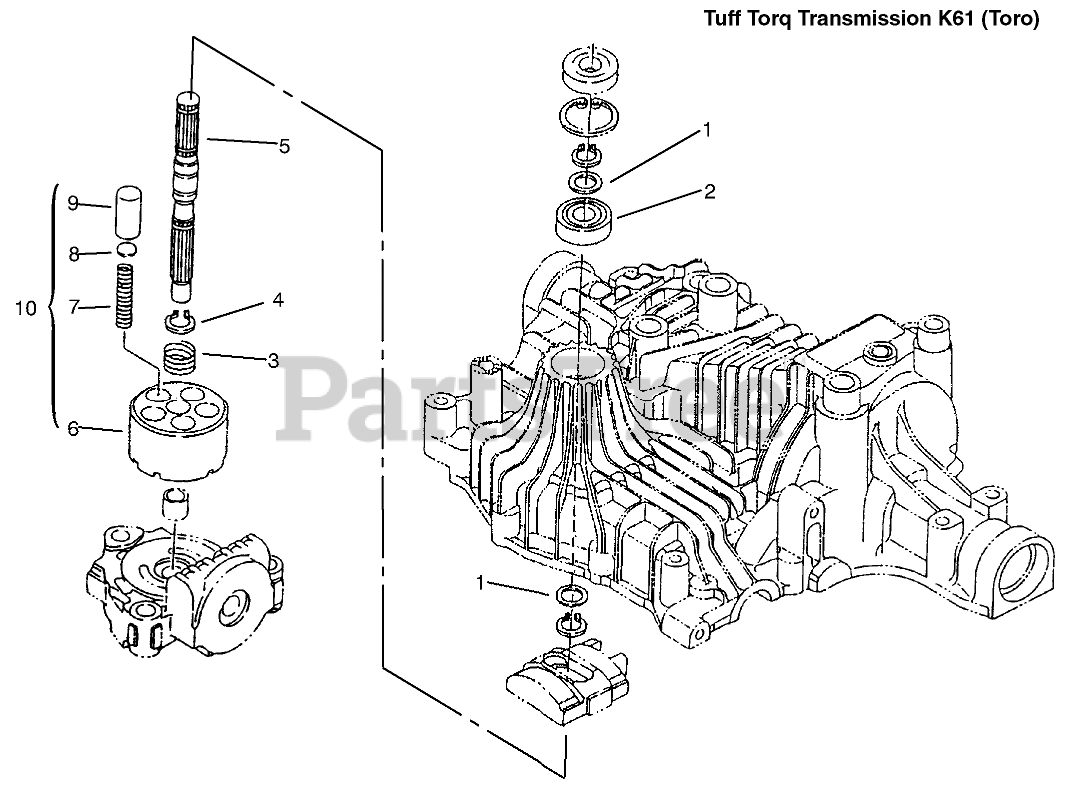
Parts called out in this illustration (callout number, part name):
1	WASHER
2	BEARING-BALL
3	SPRING
4	RING-SNAP
5	SHAFT - PUMP
6	Block-Cylinder
8	Washer
10	ASM - CYCLINDER INC 6-9
